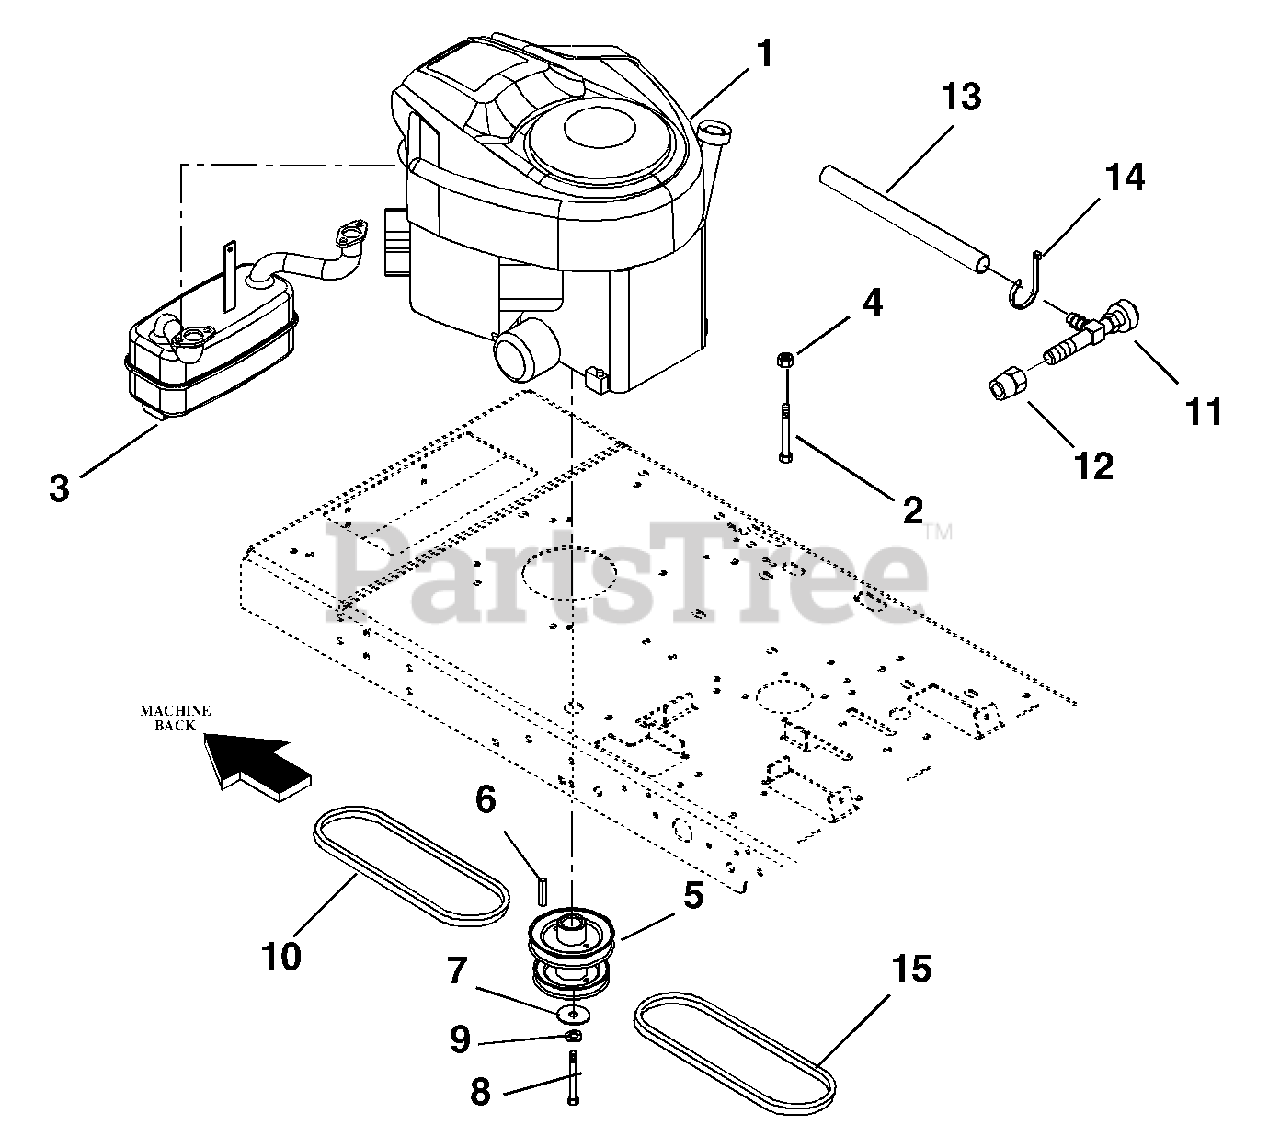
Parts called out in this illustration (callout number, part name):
1	ENGINE GROUP - 20HP ARIENS
2	@SCR-TAP .31-18X1.50 HWH TR YZ
3	MUFFLER ASSEMBLY
4	@NUT-LK-TOP-FLG .31-18 YWZC
5	ENGINE SHEAVE 4.50
6	KEY-SQ .25 X 2.50 X .25 SAE
7	WSHR-FL-STL .469X2.00X.25 YWZC
8	BLT-HEX .44-20X3.00 GR5 YWZC
9	@WSHR-LK .44X.109 REG YWZC
10	V-BELT, HA-WRAPPED
11	COCK, OIL DRAIN
12	ADAPTER, OIL DRAIN
13	TUBE OIL DRAIN
14	CABLE TIE LG 5-1/2
15	V-BELT, HB-WRAPPED
